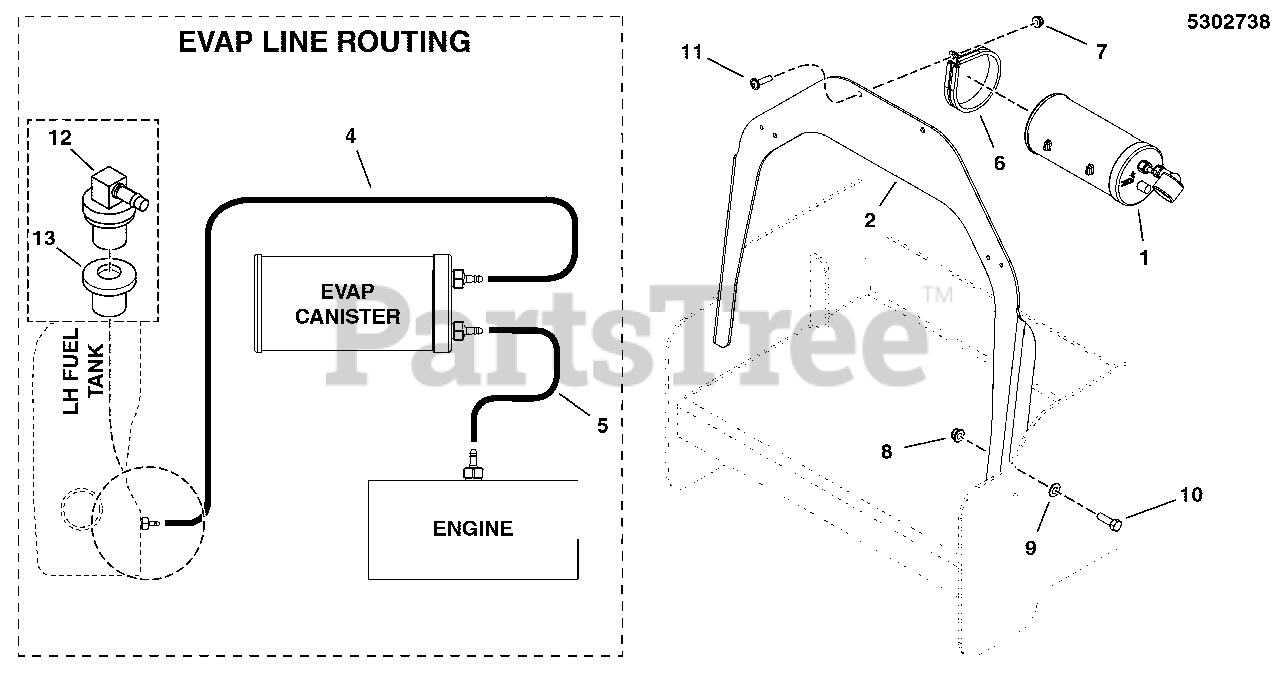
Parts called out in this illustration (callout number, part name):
1	CNSTR, CARB, 6 GAL
2	BRACKET, CARB CANISTER, S50X - BLK
3	DECAL, EPA CERT, ZTRS
4	HOSE, VAPOR, 5MM ID, 29.50 LG
5	HOSE, VAPOR, 5MM ID, 36.50 LG
6	CLAMP, 3" ID, CUSHIONED, STAINLESS
7	NUT, 1/4-20 HEX NYLOCK FLANGE (5025391)
8	NUT, 5/16-18 HEX NYLOCK FLANGE
9	WASHER, 5/16 SAE
10	BOLT, 5/16-18 X 1 GD5 YZ
11	SCREW, 1/4-20 X 3/4 ALLEN BH
12	REMOTE VENT ASSEMBLY, NO VALVE (SV)
13	GROMMET (209043)(SV)
